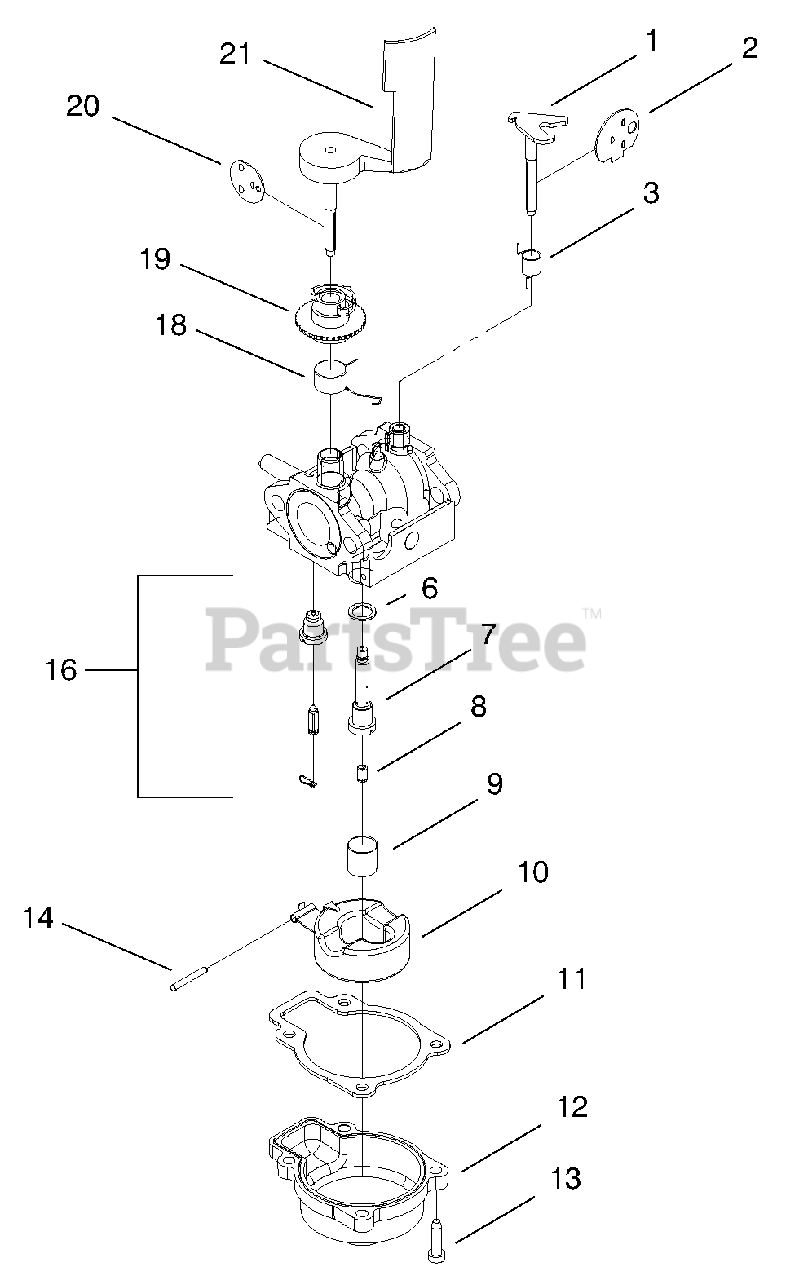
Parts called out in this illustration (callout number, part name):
1	Shaft-Choke
2	Disc-Choke
3	Spring-Choke
8	Jet-Main 77.5
9	Filter-Fuel
10	Float&arm Ay
12	Chamber-Float
13	Screw-HH
16	Val/Seat-Float
18	Spring-Gov.
19	Airvane-Collar
20	Disc-Throttle
21	Air Vane&shaft
